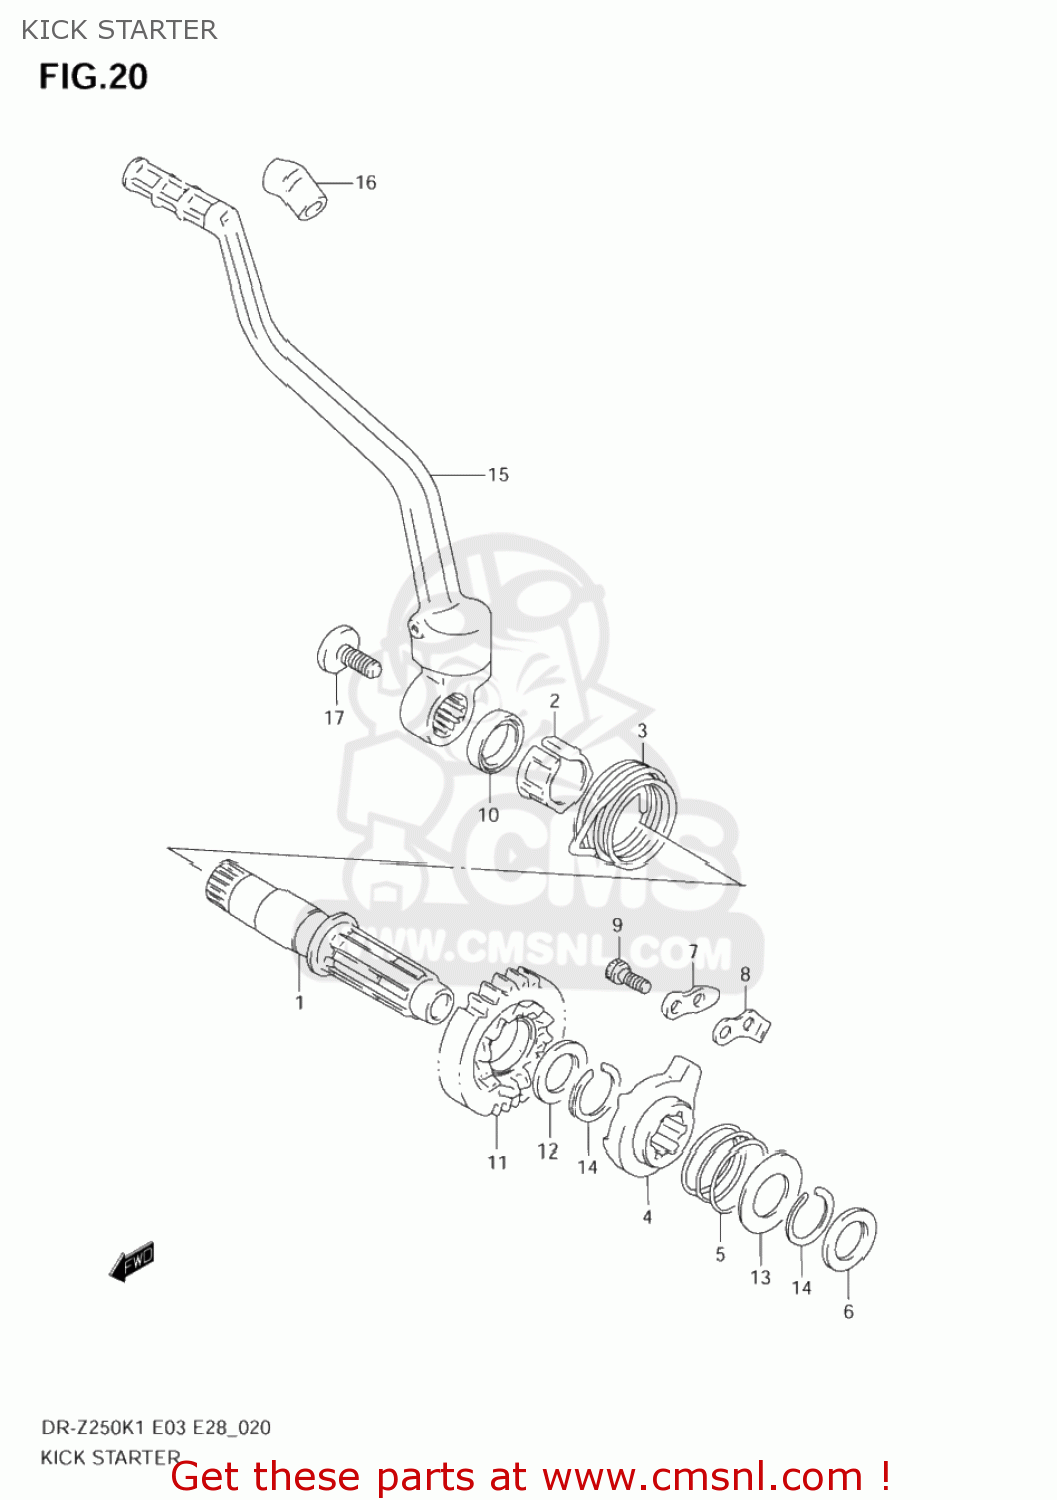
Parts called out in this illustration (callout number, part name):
1	SHAFT,KICK STARTER
2	GUIDE,KICK STARTER SFT SPRING
3	SPRING
4	STARTER,KICK
5	SPRING
6	SHIM(17X26X1)
7	GUIDE,KICK STARTER
8	STOPPER,KICK STARTER
9	BOLT(6X16)
10	SEAL,OIL(20X27X6)
11	GEAR,KICK STARTER(NT:23)
12	SHIM(22X28X1)
13	SHIM(22X36X1)
14	CIRCLIP
15	LEVER ASSY,KICK STARTER
16	COVER,KICK STARTER LEVER
17	BOLT(8X14)
